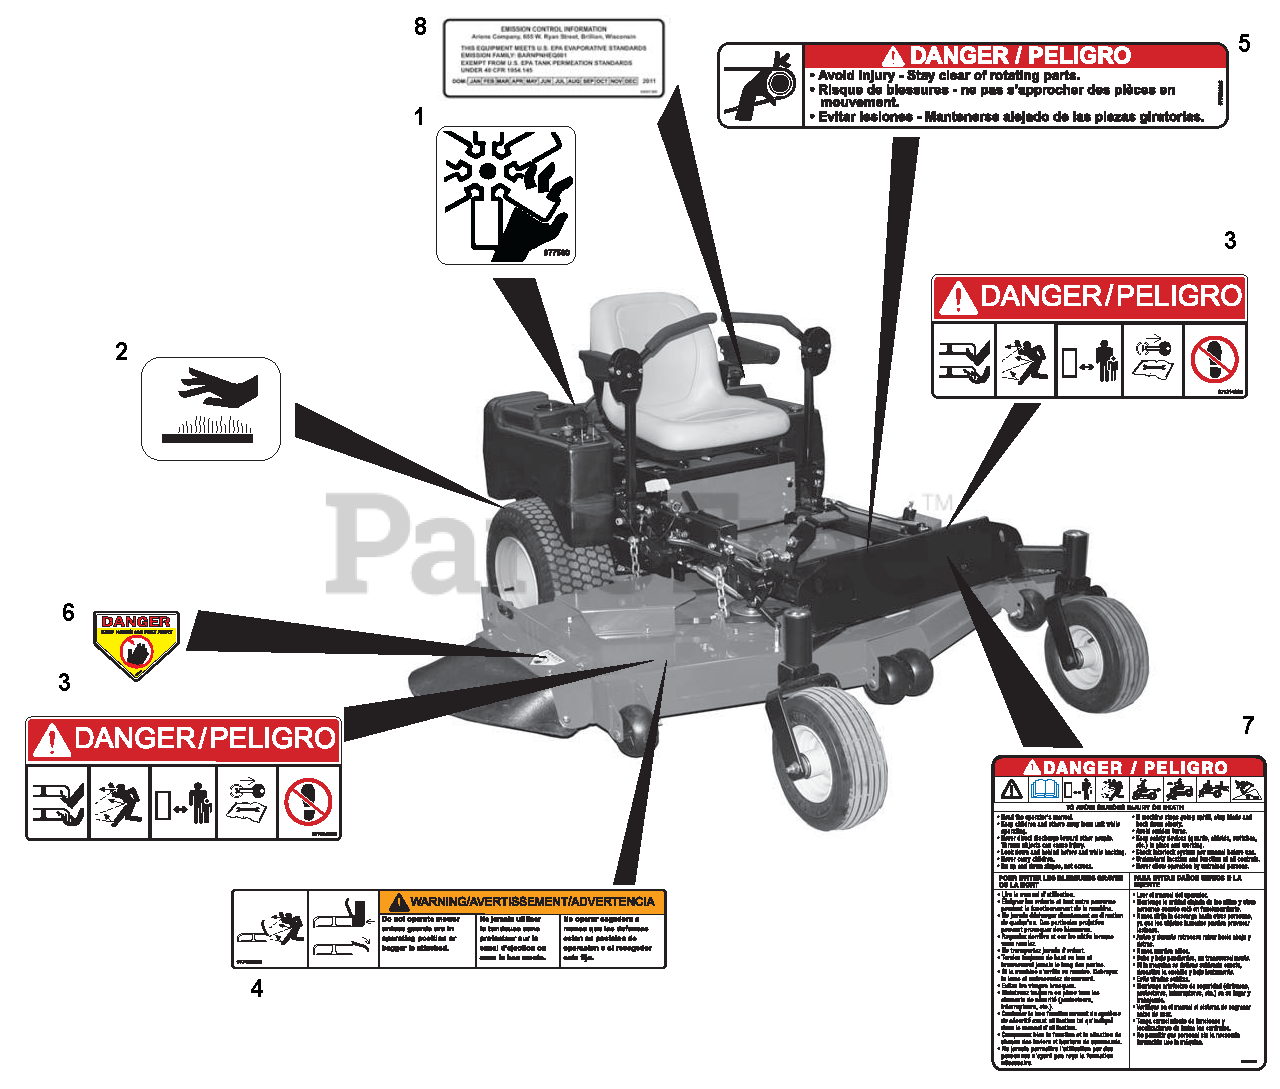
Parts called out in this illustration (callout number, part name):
1	DECAL, DANGER FAN
2	DECAL, HOT SURFACE
3	DECAL, MOWER PAN DANGER
4	DECAL, WARNING
5	DECAL- DANGER
6	DECAL, DANGER
7	DECAL, DANGER - BILINGUAL
8	LABEL, EPA NON-COMPLIANT TANK
